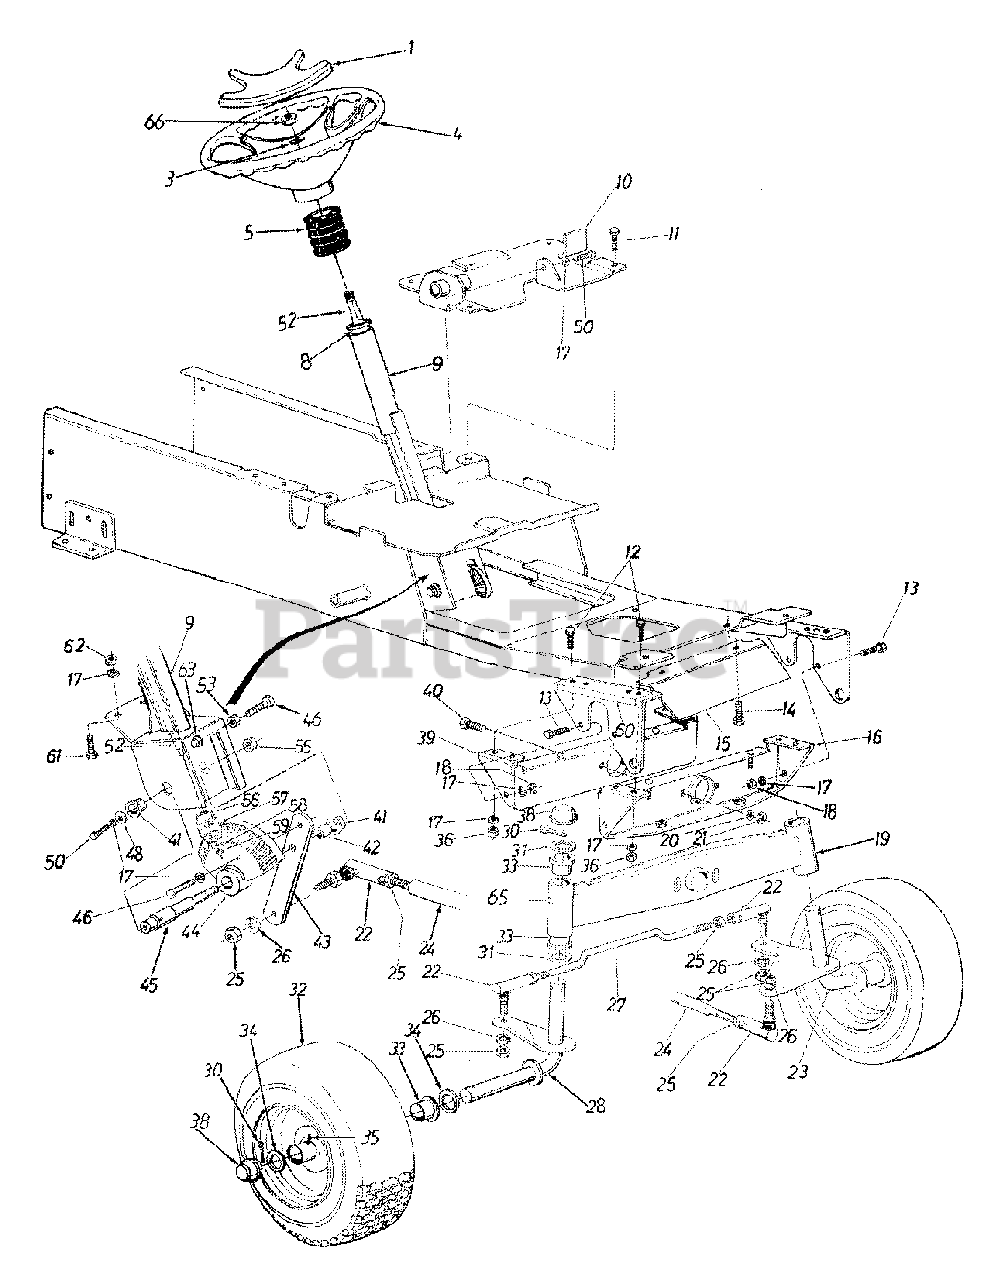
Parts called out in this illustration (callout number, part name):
1	Steering Wheel Insert
2	Hex L-Bolt 5/16-18 x 1" Lg.
3	Bell-Wash. 5/16" I.D.
4	Steering Wheel
5	Steering Bellow
8	Ball Brg. .63" I.D. x 1.38" O.D.
9	Steering Column Ass'y.
12	Hex Bolt 3/8-16 x 1.50" Lg.
13	Hex Bolt 3/8-16 x 1.00" Lg.
14	Hex Wash. S.F. Tap Scr. 3/8-16 x 1.25" Lg.
18	Hex Nut 3/8-16 Thd.
19	Pivot Bar Ass'y.
20	Bell-Wash. 3/8" I.D.
21	Hex Cent. L-Nut 3/8-16 Thd.
22	Drag Link End
23	Axle Ass'y. - L.H.
24	Drag Link
25	Hex Nut 1/2-20 Thd.
26	L-Wash. 1/2" I.D.
27	Tie Rod
28	Axle Ass'y. - R.H.
30	Cotter Pin 3/16" Dia. x 1.50" Lg.
31	Fl-Wash. 1.00" I.D. x 1.62" O.D.
33	Flange Brg. 1" I.D.
34	Fl-Wash. 1" I.D. x 1.25" O.D.
35	Grease Fitting
36	Hex Nut 3/8-16 Thd.
38	Dust Cover
41	Flange Brg. w/Flats .753" I.D.
42	Steering Gear Shaft Spacer
43	Steering Arm
44	Bevel Gear
45	Steering Gear Shaft
46	Hex Bolt 3/8-16 x 1.50" Lg.
48	Fl-Wash. .406" I.D. x 1.25" O.D.
50	Hex Bolt 3/8-16 x .75" Lg.
52	Steering Shaft
53	Hex Jam Nut 3/8-16 Thd.
55	Hex Ins. L-Nut 1/2-20 Thd.
56	Hex Flange Brg. .630 I.D.
57	Pinion Gear
58	Fl-Wash. 3/8" Dia.
59	Hex Cent. L-Nut 5/16-24 Thd.
62	Hex Nut 3/8-24 Thd.
63	Cap
65	Grease Fitting
